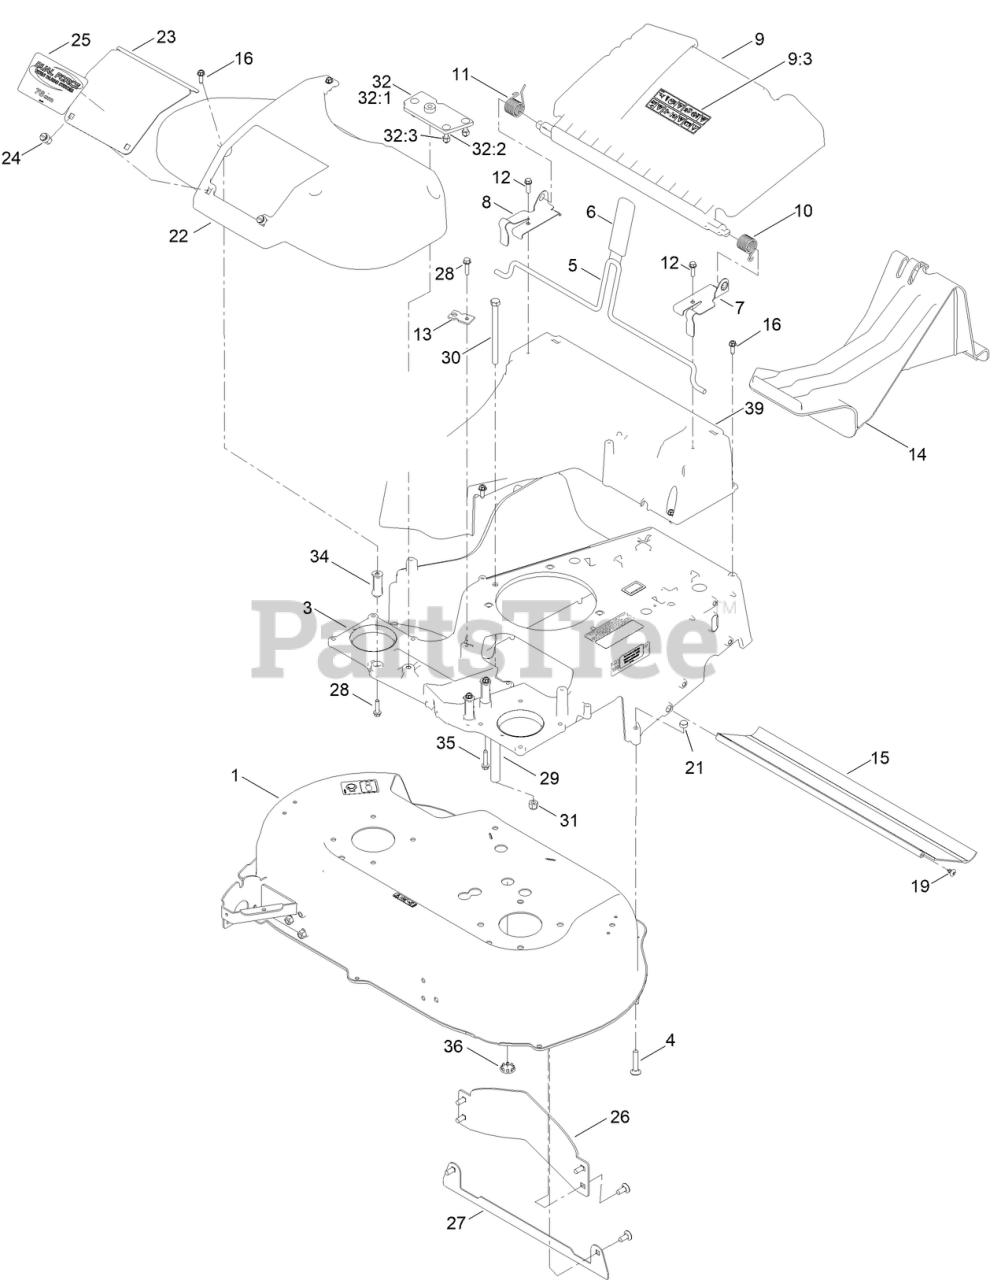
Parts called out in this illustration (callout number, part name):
1	HOUSING ASM
3	FRAME-30"
4	BOLT-CAR
5	ROD-RELEASE, HANDLE
6	GRIP-LEVER
7	BRACKET-DOOR, LH
8	BRACKET-DOOR, RH
9	REAR DEFLECTOR ASM
9:3	DECAL-WARNING
10	SPRING-TORSION
11	SPRING-TORSION
12	SCREW-PLASTITE, HWH
13	BRACKET-CABLE, TRACTION
14	PLUG-MULCH
15	SHIELD-TRAILING
16	SCREW-HWHTF
19	SCREW-THD
21	NUT-HEX
22	COVER-BELT
23	DOOR-ACCESS
24	FASTENER
25	DECAL-ACCESS PANEL
26	BAFFLE-CONTROL
27	PLATE-DECK
28	SCREW-HWHTF
29	SPACER-SHIELD
30	SCREW-HH
31	NUT-HEX
32	FRAME PLATE KIT
32:1	PLATE-FRAME
32:2	SCREW-CARR
32:3	NUT-LOCK, NI
34	SPACER-FRAME, 30 IN.
35	SCREW-HWHTF
36	PLUG-BUTTON
